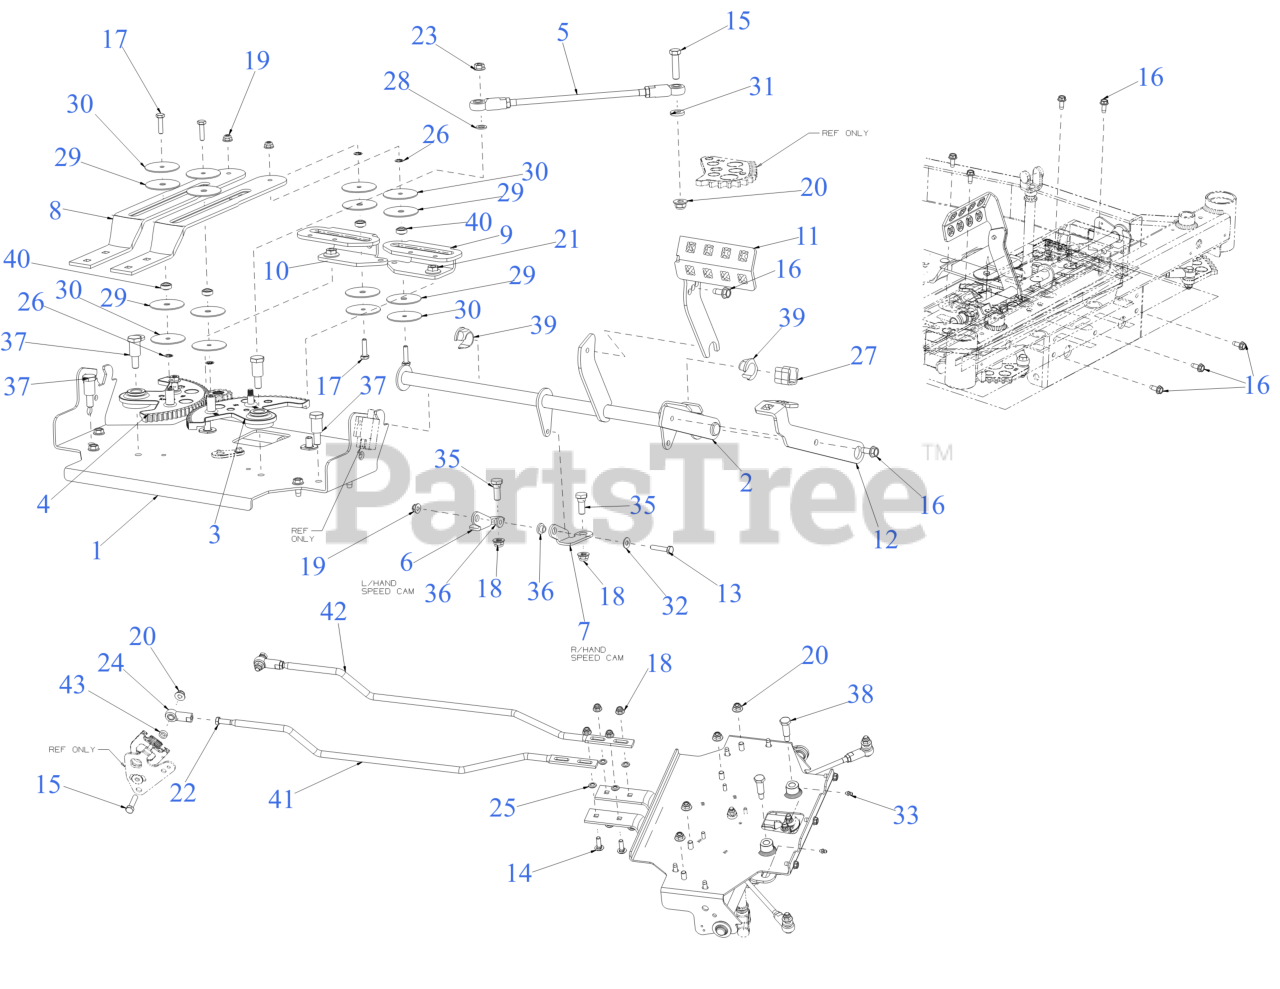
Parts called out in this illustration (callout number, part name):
1	STEERING SUPPORT PLATE
2	DRIVE PEDAL SHAFT
3	STEERING GEAR ASSEMBLY (RH)
4	STEERING GEAR ASSEMBLY (LH)
5	STEERING TIE ROD
5	BALL JOINT
5	HEX JAM NUT 3/8X24
6	PEDAL SHAFT BRACKET (LH)
7	PEDAL SHAFT BRACKET (RH)
8	CONTROL LINK
9	SPEED CAM PLATE (RH)
10	SPEED CAM PLATE (LH)
11	DRIVE PEDAL (FORWARD)
12	DRIVE PEDAL (REVERSE)
13	SCREW 1/4-20 x 1.0
13	HEX SCREW 1/4-20 x 1.25
14	CARRIAGE BOLT 5/16-18 x 1.00
15	SCREW 3/8-16 x 1.50
16	SCREW 5/16-18 x .750
17	SCREW 1/4-20X1.0 GR5
18	FLANGE LOCK NUT 5/16-18
19	FLANGE LOCK NUT
21	FLANGE LOCK NUT
22	HEX JAM NUT 3/8X24
23	HEX FLANGE NUT
24	BALL JOINT
26	RETAINER-BOLT .25ID x .50OD
27	SPACER-LIFT SHAFT
28	FLAT WASHER
29	FLAT WASHER
30	FLAT WASHER
31	FLAT WASHER
32	FLAT WASHER .271:.630:.065
33	GREASE ZERT 1/4-28
35	SHOULDER SCREW .437
36	SHOULDER SPACER
37	SHOULDER SCREW .625 x .875 x 3/18
38	SHOULDER SCREW .50
39	HEX FLANGE SPLIT BEARING
40	BALL BEARING .25 x .625
41	HYDRO LINK ROD (LH)
42	HYDRO LINK ROD (RH)
43	SPACER-.380 ID x .625 OD x .227
